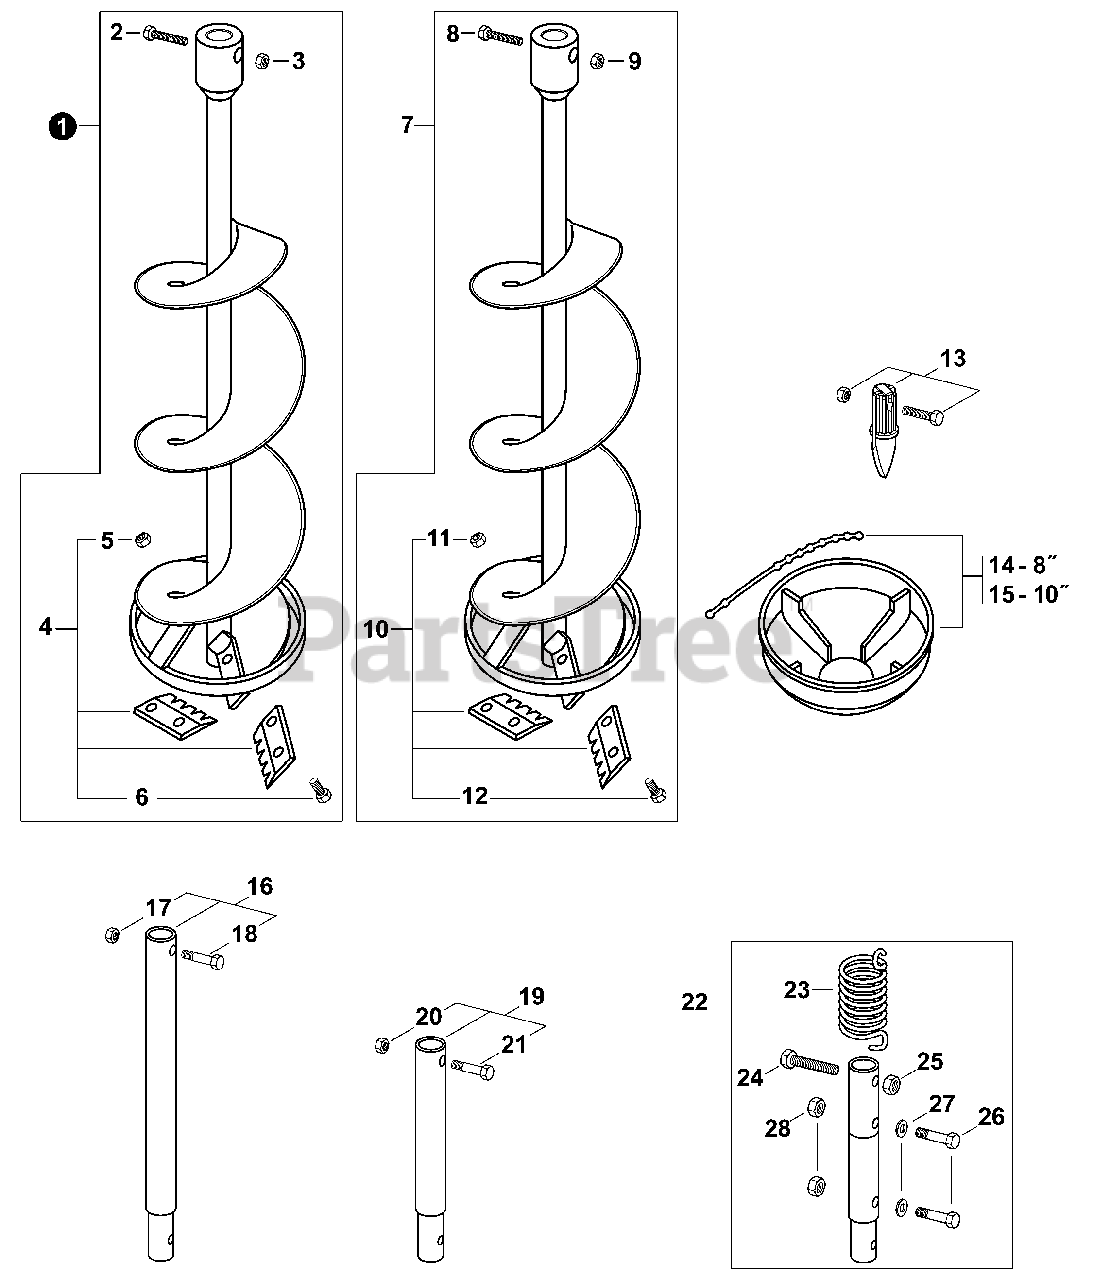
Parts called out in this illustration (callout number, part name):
1	DUAL BLADE ICE AUGER - 8" DIA.
4	ICE AUGER DUAL BLADE KIT - 8" DIA.
7	DUAL BLADE ICE AUGER - 10" DIA.
10	ICE AUGER DUAL BLADE KIT - 10" DIA.
13	ICE AUGER POINT KIT
14	ICE AUGER COVER - 8"
15	ICE AUGER COVER - 10"
16	EXTENSION SHAFT - 18" (7/8" DIA)
19	EXTENSION SHAFT - 12" (7/8" DIA)
22	ADAPTER W/SPRING - 7/8" TO 1" DIA.
23	SPRING, TENSION
